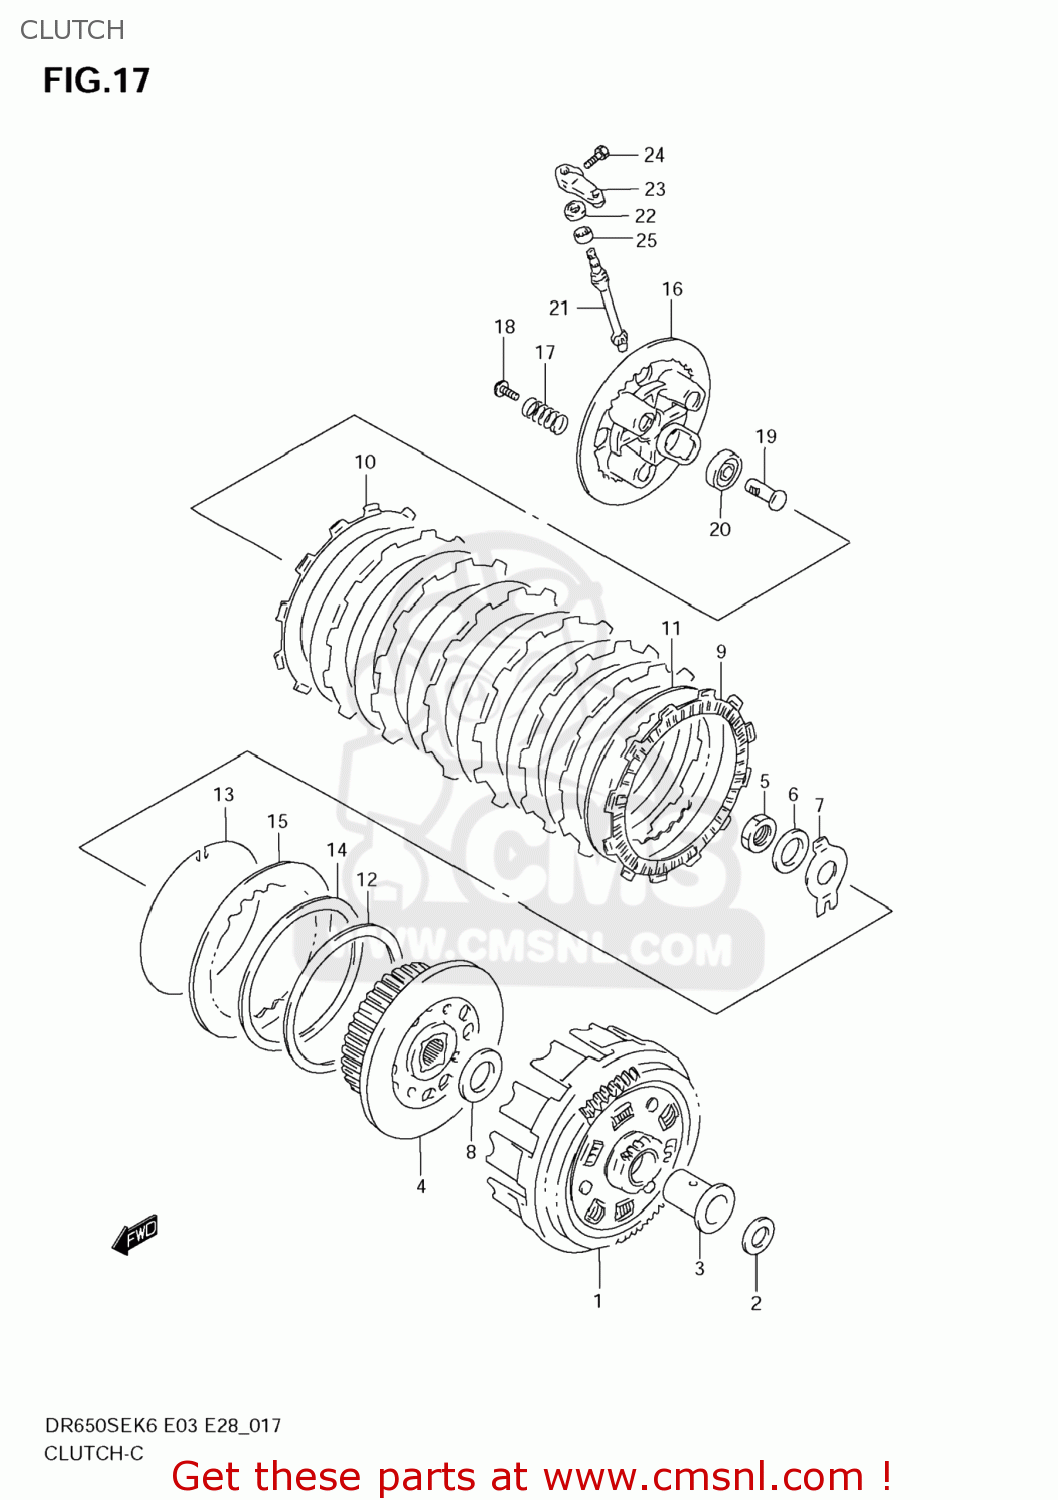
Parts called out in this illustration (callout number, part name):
1	GEAR ASSEMBLY,PRIMARY DRIVE
2	WASHER(22X32X3)
3	SPACER,PRIMARY DRIVEN GEAR
4	HUB,CLUTCH SLEEVE
5	NUT
6	WASHER
7	WASHER
8	WASHER(22X44X2)
9	PLATE,CLUTCH DRIVE (NAS)
10	PLATE,CLUTCH DRIVE (NAS)
11	PLATE,CLUTCH DRIVEN NO.1 (NAS)
12	SEAT,WAVE WASHER
13	RING,STOPPER
14	WASHER
15	PLATE,CLUTCH DRIVEN (NAS)
16	DISC,CLUTCH PRESSURE
17	SPRING
18	BOLT(6X16)
19	RACK,CLUTCH RELEASE
20	BEARING
21	PINION,CLUTCH RELEASE
22	SEAL,OIL(10X17X5)
23	ARM,CLUTCH RELEASE
24	BOLT
25	BEARING(12X16X10)
